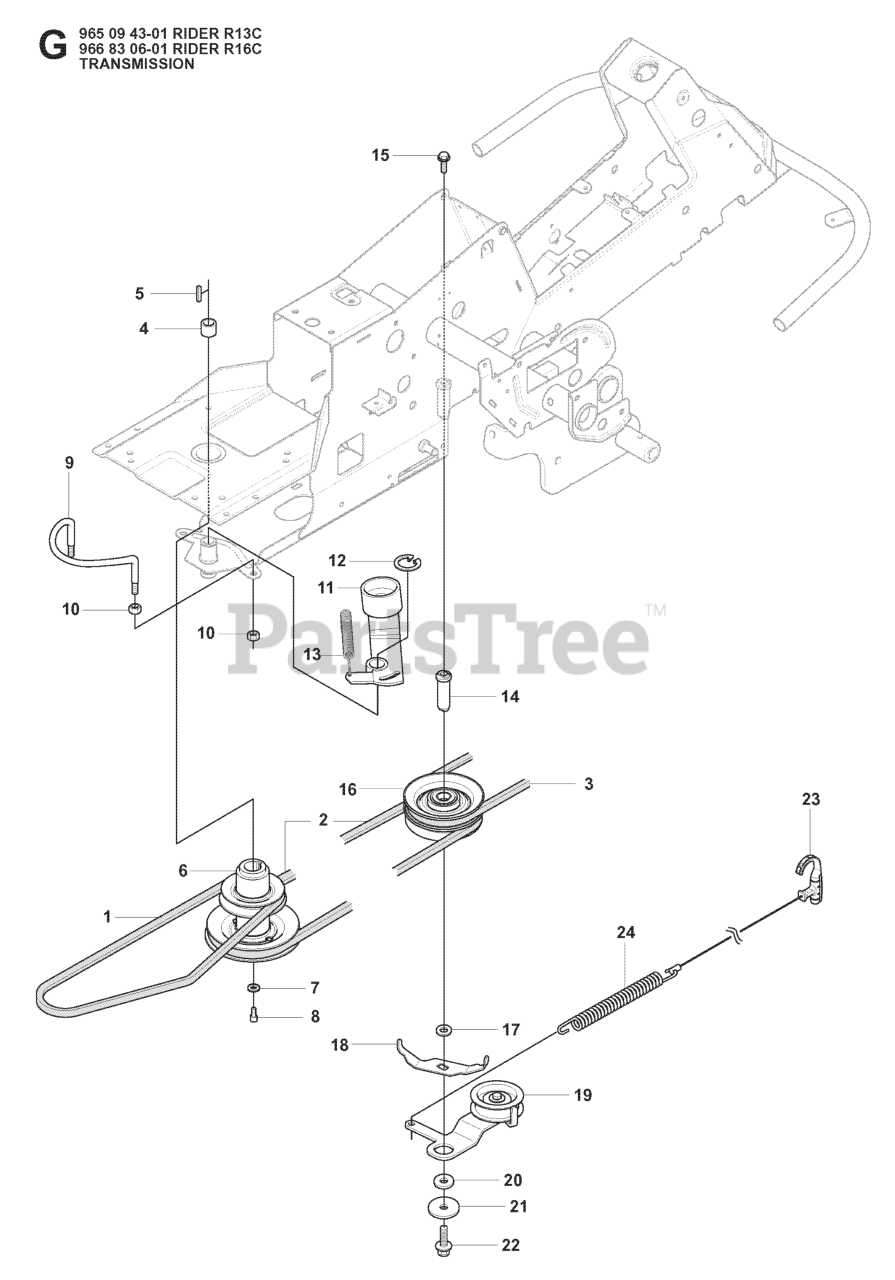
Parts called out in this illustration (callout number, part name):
9	BELT GUIDE
10	NUT
12	RETAINING RING SGA 25
14	SHAFT
18	BELT GUIDE
19	BELT TENSIONER ASSY
22	BOLT
